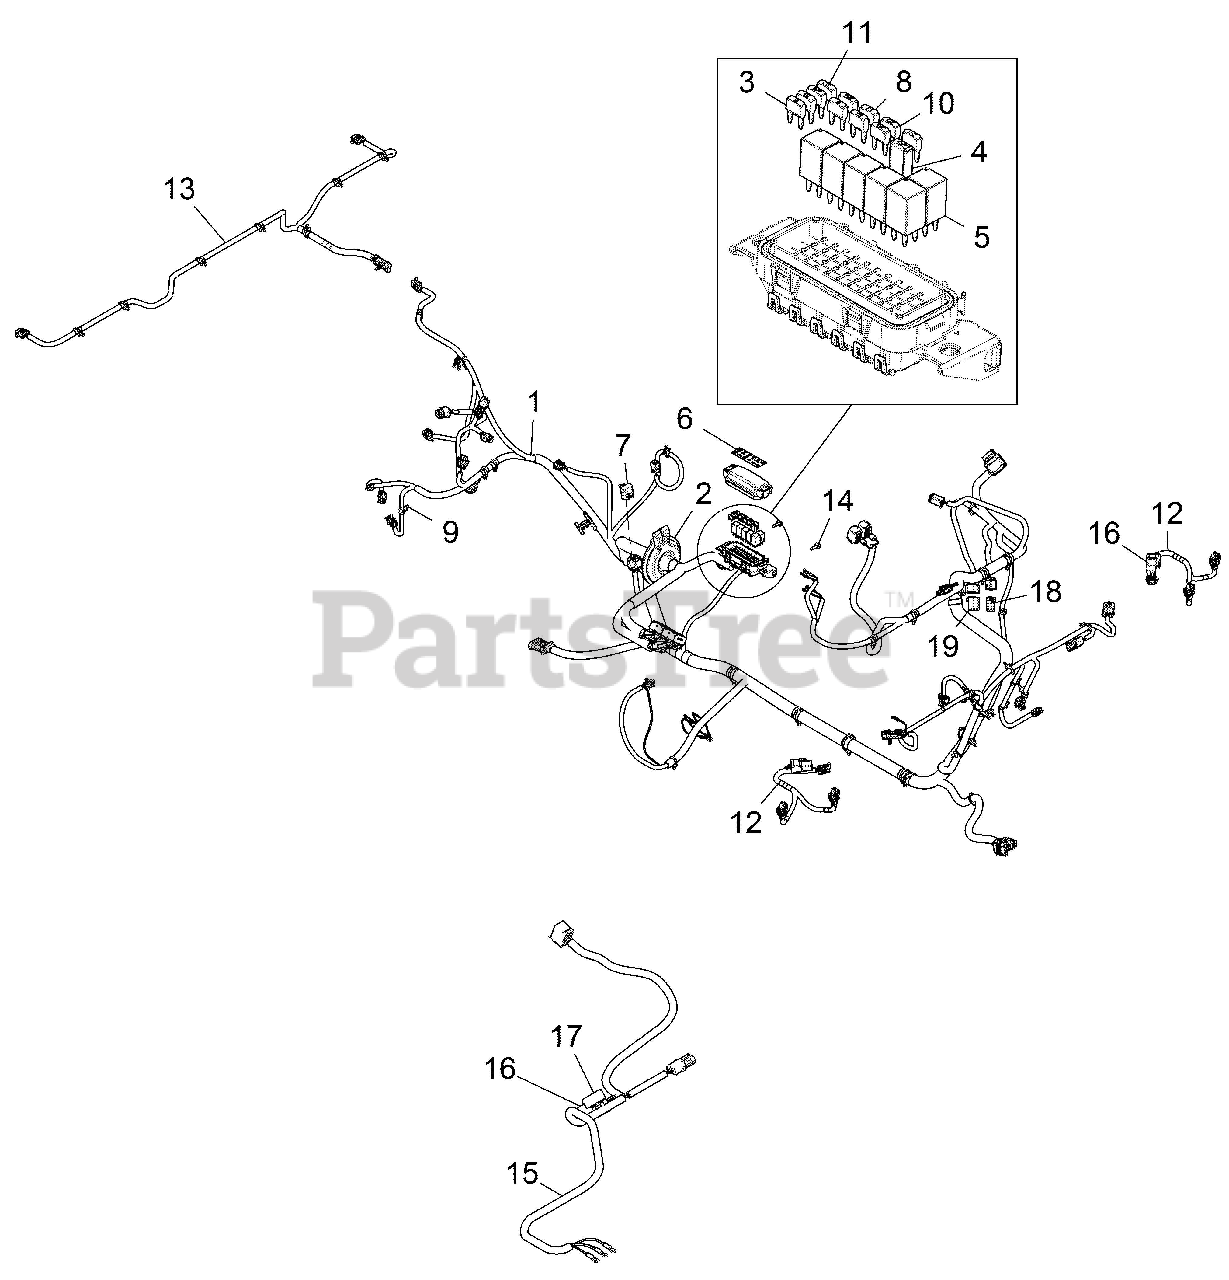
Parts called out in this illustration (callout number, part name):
1	HARNESS-CHASSIS,570,EPS
2	GROMMET-CHASSIS HARNESS
3	FUSE-5A,MINI BLADE
4	BREAKER-CIRCUIT,20 AMP
5	RELAY-SPST,SERIES 303,SEALED
6	DECAL, RELAY/FUSE BLOCK
7	COVER-DIAGNOSTIC,W/CLIP
8	FUSE,IGN.10 AMP,(10)
9	CLIP-ROUTING
10	FUSE, 20 AMP, PARK
11	FUSE,MAIN,30 AMP,(10)
12	HARNESS-HEADLIGHT,ARIENS
13	HARNESS-BOX-ARIENS SPLY
14	SCR-M6X1.0X20,HXHD,FLG,TDFM,BL
15	HARNESS-BOX,LIFT
16	RELAY-MICRO,SPST,35A,SEALED
17	BREAKER-CIRCUIT,20 AMP,SEALED
18	CONNECTOR-CAP,EPS SIGNAL
19	CONNECTOR-CAP,EPS POWER
